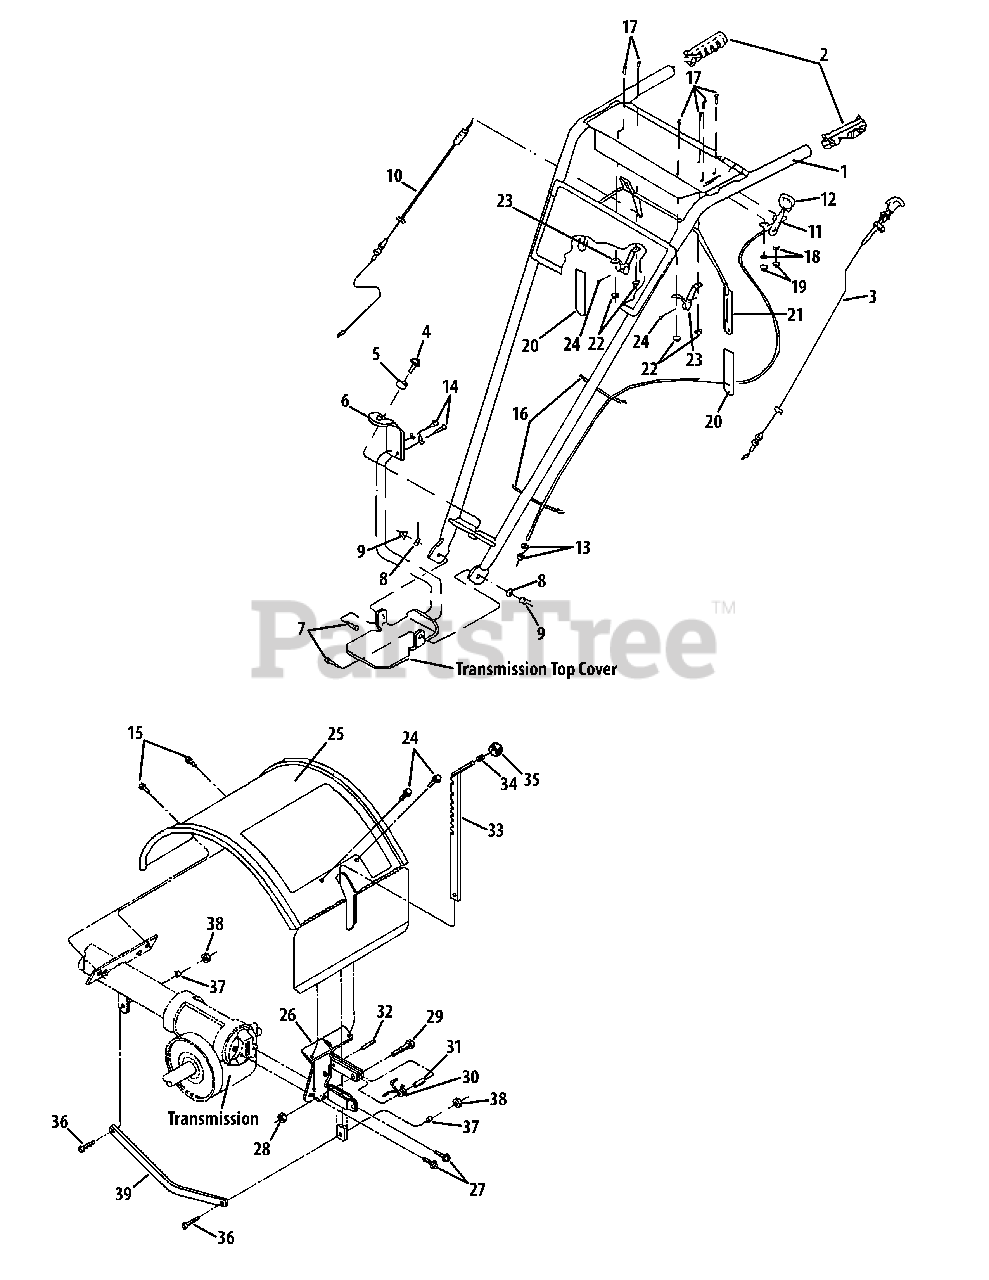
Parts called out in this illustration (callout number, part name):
1	Handlebars
3	Reverse Clutch Control Cable
4	Hex Flange Screw, 3/8-16
5	Keyed Washer
6	Handlebar Hgt. Adjustment Bracket
7	Hex Hd. Screw, 3/8-16 x 1
8	Plain Washer, 3/8
9	Hex Locknut, 3/8-16
10	Forward Clutch Control Cable
11	Wheel Gear Control & Cable Ass.
12	Wheel Gear Control Lever Knob
13	Hex Nut, 5/16-24
14	Self-tapping Screw, 3/8-16 x 3/4
15	Self-tapping Screw, 5/16-18 x 5/8
16	Cable Ties
17	Round Head Screw, #10-32 x 1/2
18	Lockwasher, #10
19	Hex Nut, #10-32
21	Forward Clutch Bail
23	Bail Support Bracket
24	Self-tapping Screw, 1/4-20 x 1/2
26	Hood Bracket
27	Hex Flange Screw, 5/16-18 x 5/8
28	Hex Locknut, 1/4-20
29	Hex Head Screw, 1/4-20 x 1
32	Roll Pin (spiral), 1/4 x 1
33	Depth Regulator
34	Retaining Ring
35	Depth Regulator Knob
36	Hex Head Screw, 3/8-16 x 1-1/4
37	Drag Bar Bushing
38	Hex Nut, 3/8-16
